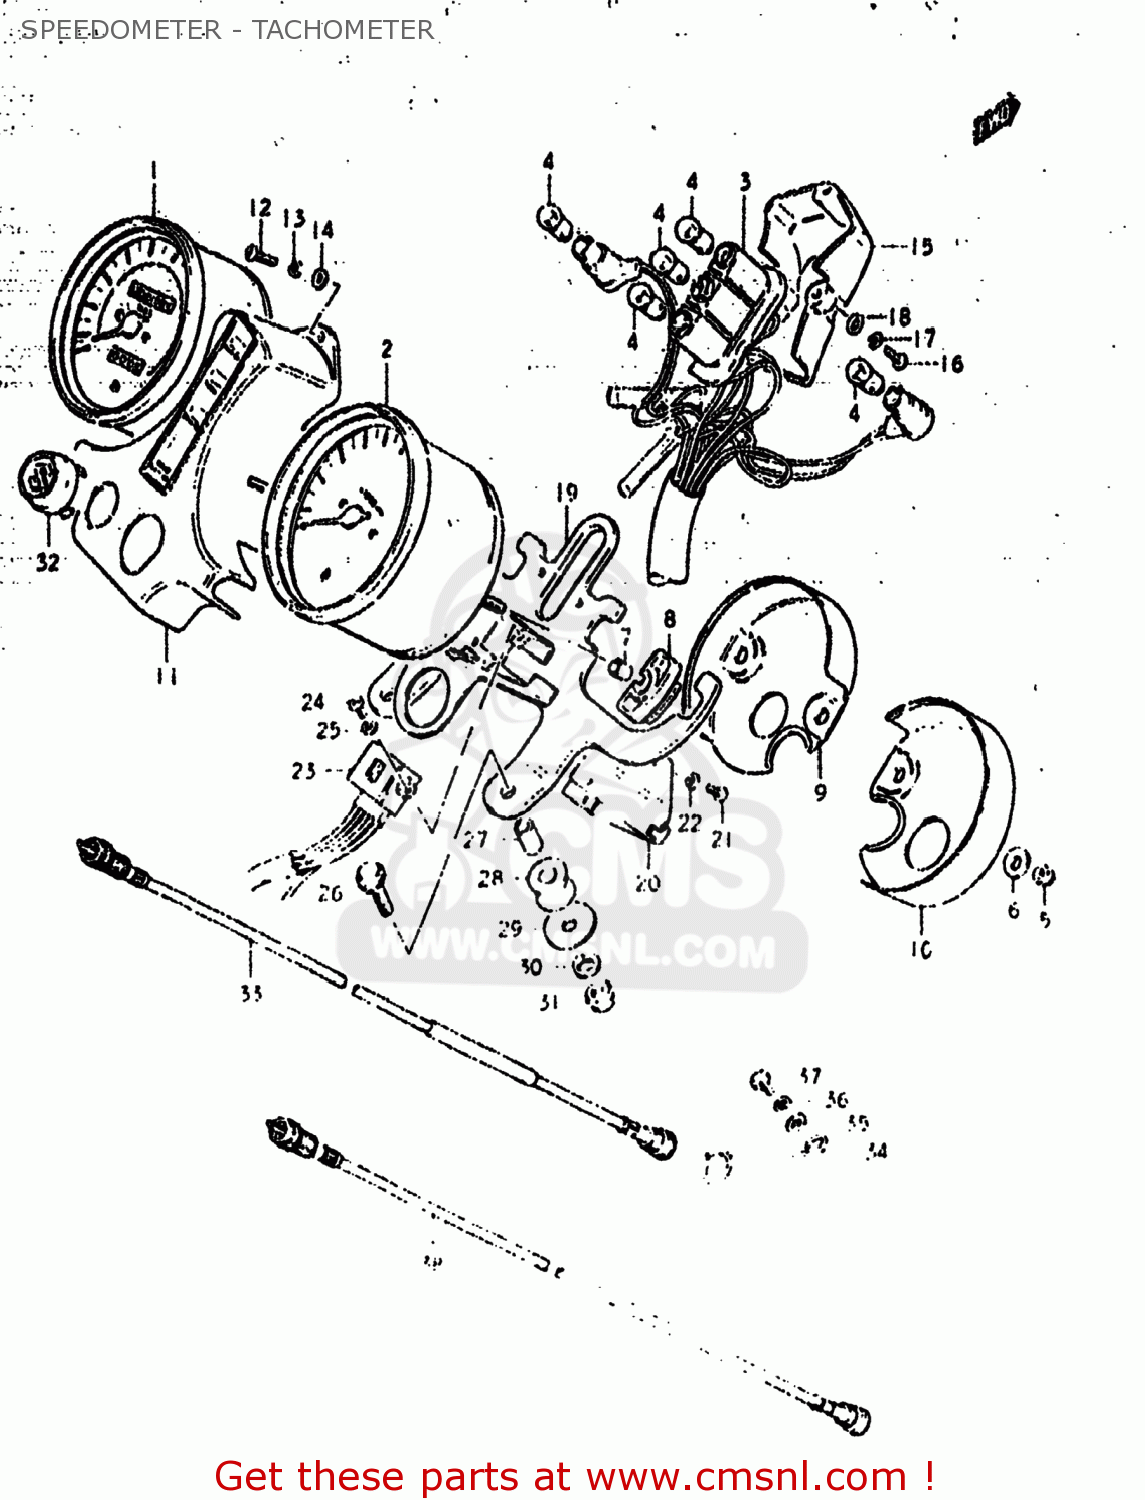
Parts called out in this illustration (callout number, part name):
1	SPEEDOMETER ASSEMBLY
2	TACHOMETER
3	SOCKET,METER
4	BULB(12V3.4W,STANLEY,A72A)
5	NUT
6	WASHER (5.5X16X1.2)
7	SPACER,METER
8	CUSHION,METER
9	COVER,METER,UNDER
10	PLATE,TACHOMETER UNDER
11	CASE,PILOT BULB
12	SCREW(4X16)
13	WASHER,PILOT UNDER CASE
14	WASHER
15	COVER
16	SCREW(4X16)
17	WASHER,PILOT UNDER CASE
18	WASHER
19	BRACKET,COMBINATION METER
20	HOLDER,COUPLER
21	SCREW
22	LOCK WASHER
23	INDICATOR ASSEMBLY,GEAR POSITION
24	SCREW
25	LOCK WASHER
26	BOLT
27	SPACER (6.1X8X15.5)
28	CUSHION
29	WASHER
30	LOCK WASHER
31	NUT
32	CAP,SPEED WARNER LAMP HOLE
33	CABLE ASSEMBLY,SPEEDOMETER
34	GUIDE,SPEEDOMETER CABLE
35	WASHER 6MM
36	LOCK WASHER
37	BOLT, UPPER
38	CABLE ASSEMBLY,TACHOMETER
